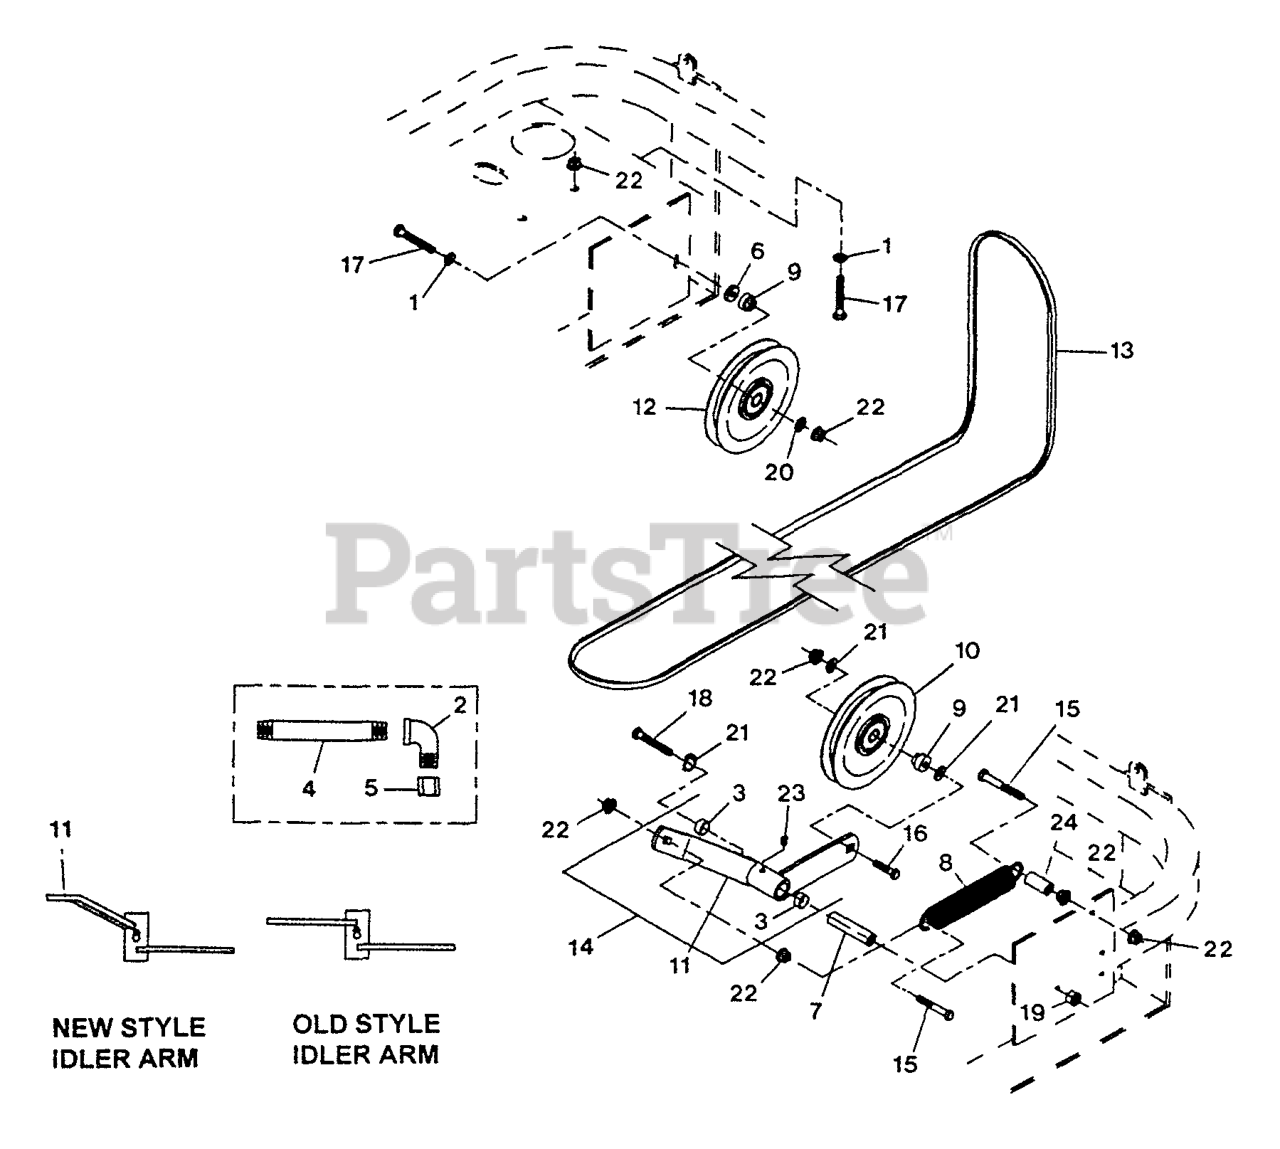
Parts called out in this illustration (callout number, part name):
2	ELBOW-90 DEG
3	SLEEVE-BEARING
4	NIPPLE
5	CAP-HEX
7	BUSHING-PIVOT, IDLER
8	SPRING-EXTENSION
9	BUSHING-IDLER
10	PULLEY-IDLER
12	PULLEY-IDLER
13	BELT,MULE DRIVE
18	SCREW-HH
